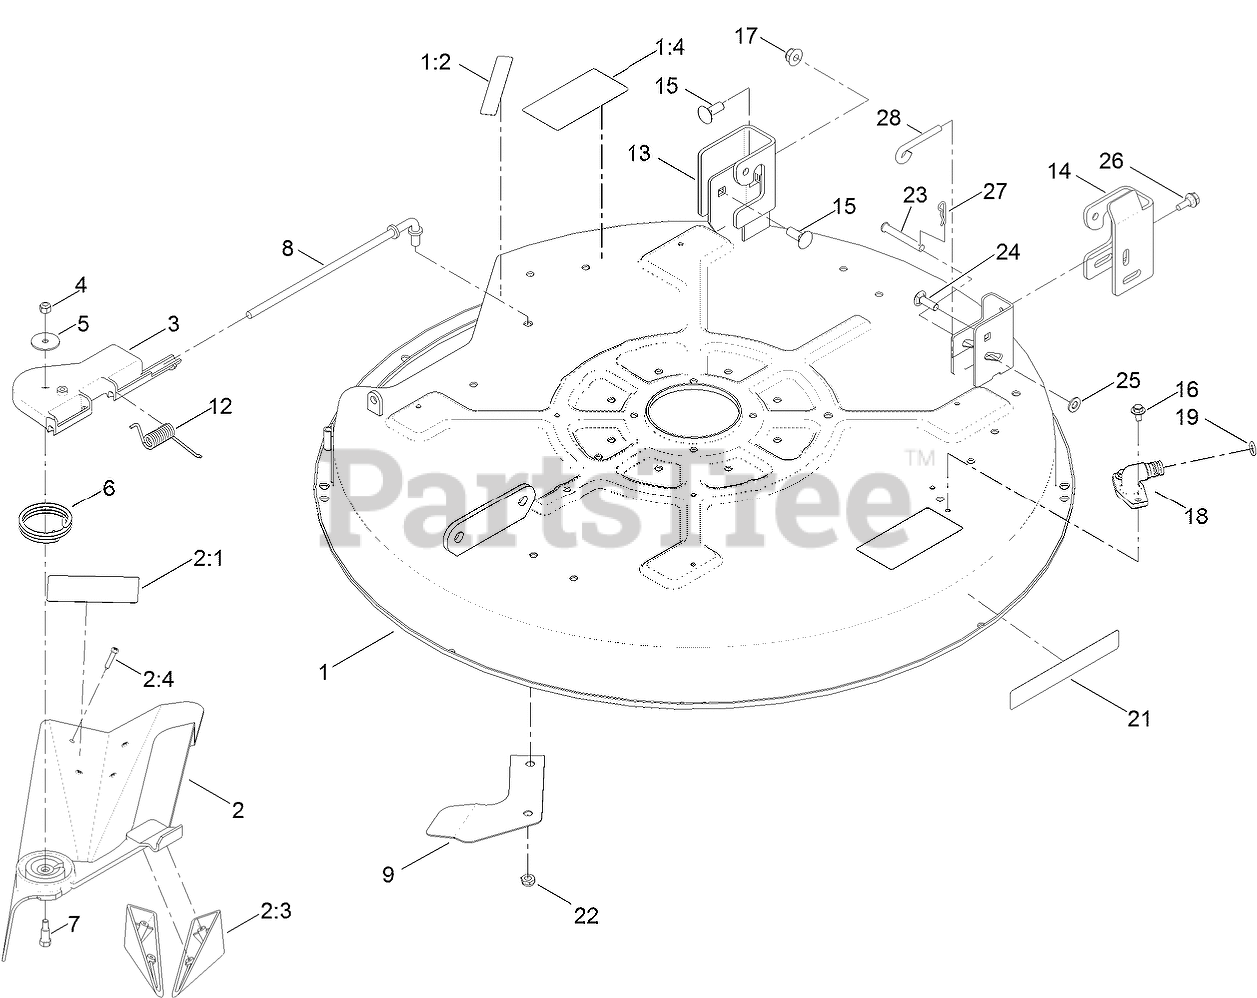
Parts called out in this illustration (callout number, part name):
1	32 INCH DECK AND DECAL ASM
1:2	DECAL-DANGER
1:4	DECAL-DANGER, DECK
2	32 INCH DEFLECTOR ASM
2:1	DECAL-DANGER
2:3	KICKER
2:4	SCREW-PPH
3	PIVOT-HINGE, DEFLECTOR
4	NUT-LOCK, NI
5	WASHER-FLAT
6	SPRING-TORSION
7	BOLT-SHOULDER
8	ROD-PIVOT
9	RAMP-DEFLECTOR
12	SPRING-TORSION
13	BRACKET-HANGER, RH
14	BRACKET-HANGER, LH
15	BOLT-CARR
16	SCREW-HHFTF
17	NUT-HF, NI
18	FITTING-WASHOUT
19	O-RING
21	DECAL-RECYCLER
22	NUT-LOCK, NI
23	PIN-CLEVIS
24	SCREW-CARR
25	WASHER-PLAIN
26	SCREW-SHOULDER, HHF
27	PIN-COTTER
28	ROD-LEVEL, DECK
